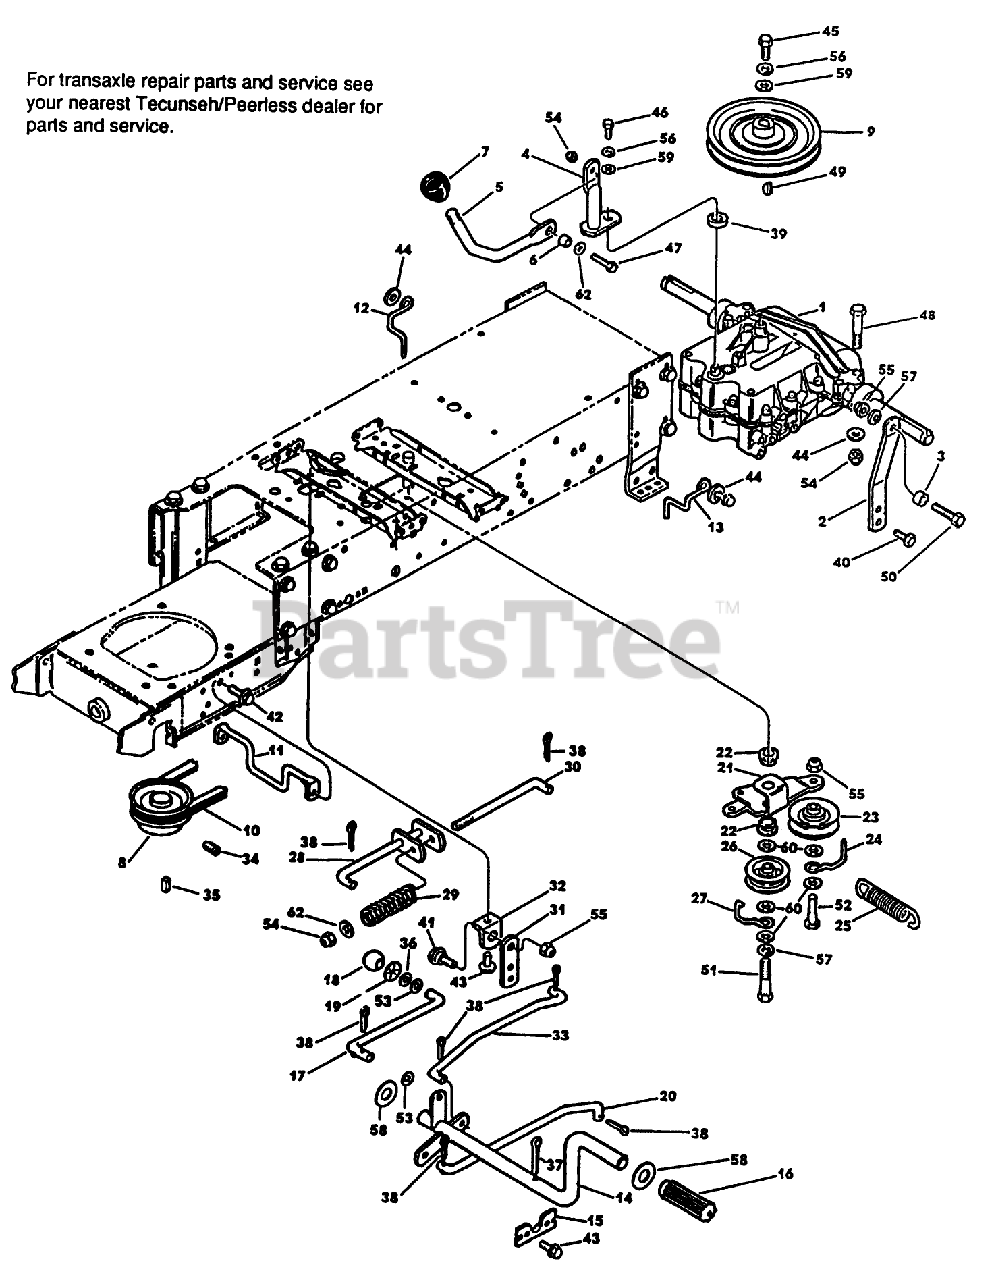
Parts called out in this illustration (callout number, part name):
4	LEVER AY-GEAR SEL.
8	SPINDLE/BLADE KIT
9	PULLEY-TRANSMISSN
12	FINGER-BELT
13	FINGER-BELT
16	GRIP - FOOT PEDAL
23	PULLEY-IDLER "V"
27	RETAINER-BELT
31	LINK - BRAKE
34	SET SCREW
46	SCREW-HEXHEAD
55	NUT-LOCKING
